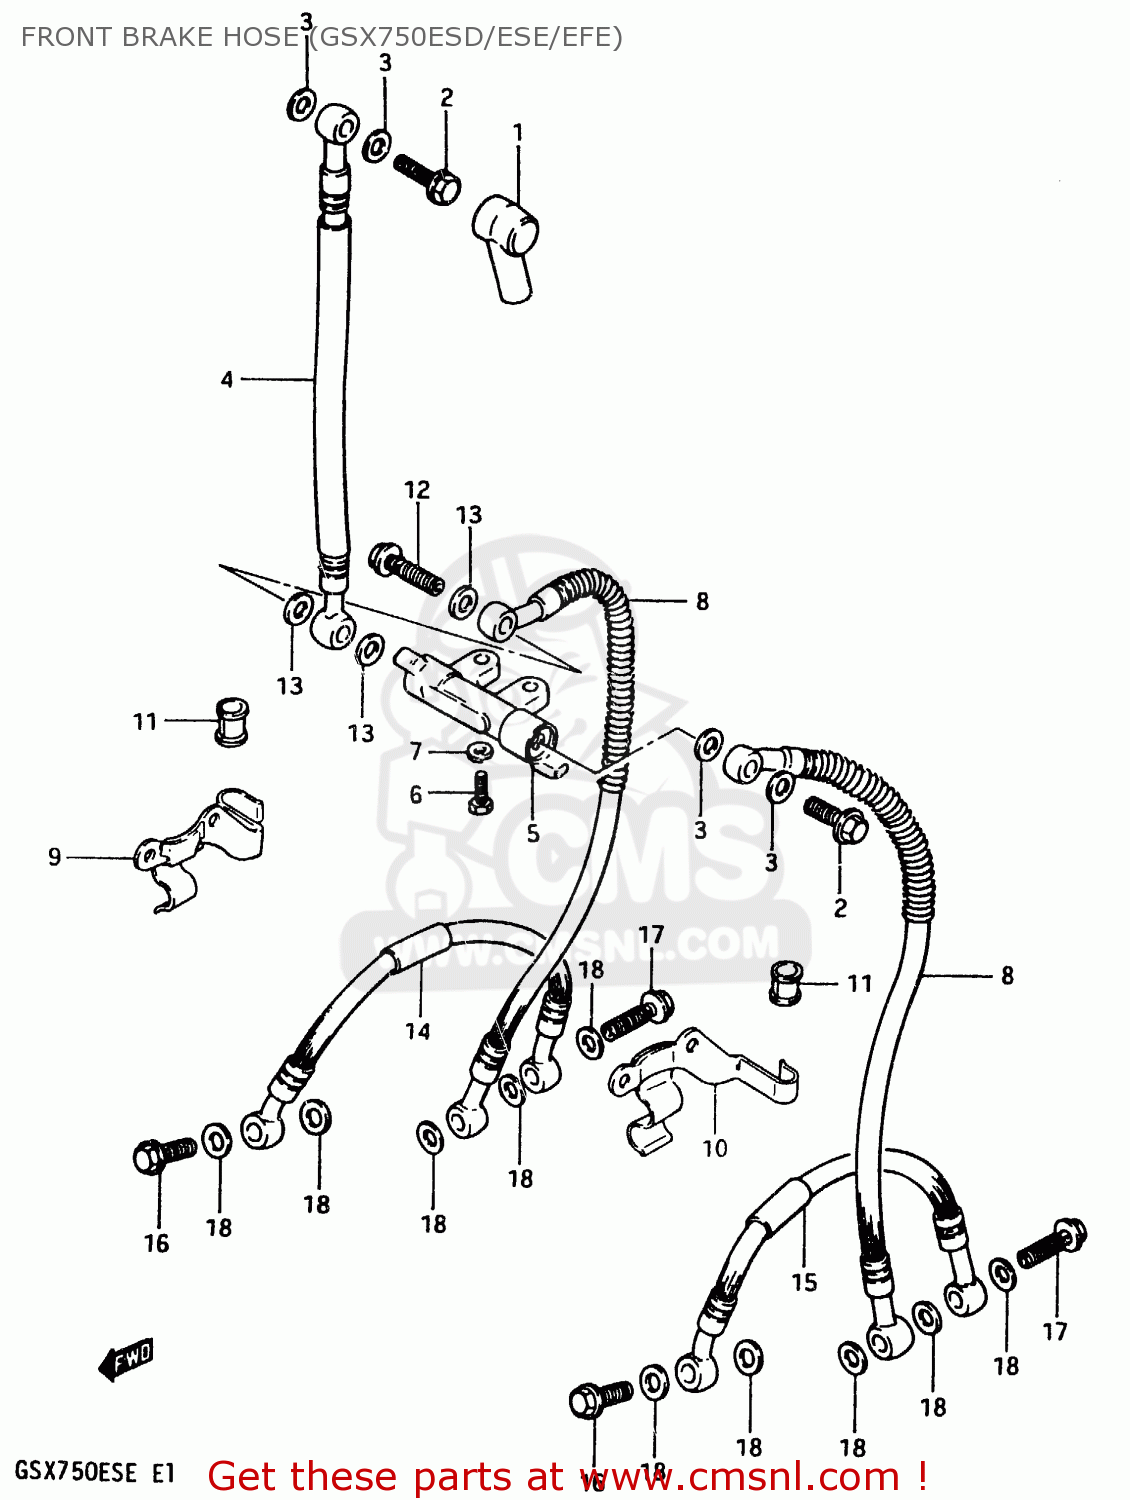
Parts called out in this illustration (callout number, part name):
1	BOOT,MASTER CYLINDER
2	BOLT UNION
3	WASHER
4	HOSE,FR BRAKE NO.1
5	JOINT,BRAKE HOSE
6	BOLT
7	LOCK WASHER
8	HOSE,FRONT BRAKE NO.2
9	CLAMP,BRAKE HOSE,RIGHT
10	CLAMP,BRAKE HOSE,LEFT
11	BUSH,BRAKE HOSE GUIDE,NO.2
12	BOLT,UNION
13	WASHER
14	HOSE,ANTI-NOSE DIVE
15	HOSE,ANTI-NOSE DIVE
16	BOLT UNION
17	BOLT,UNION
18	WASHER
